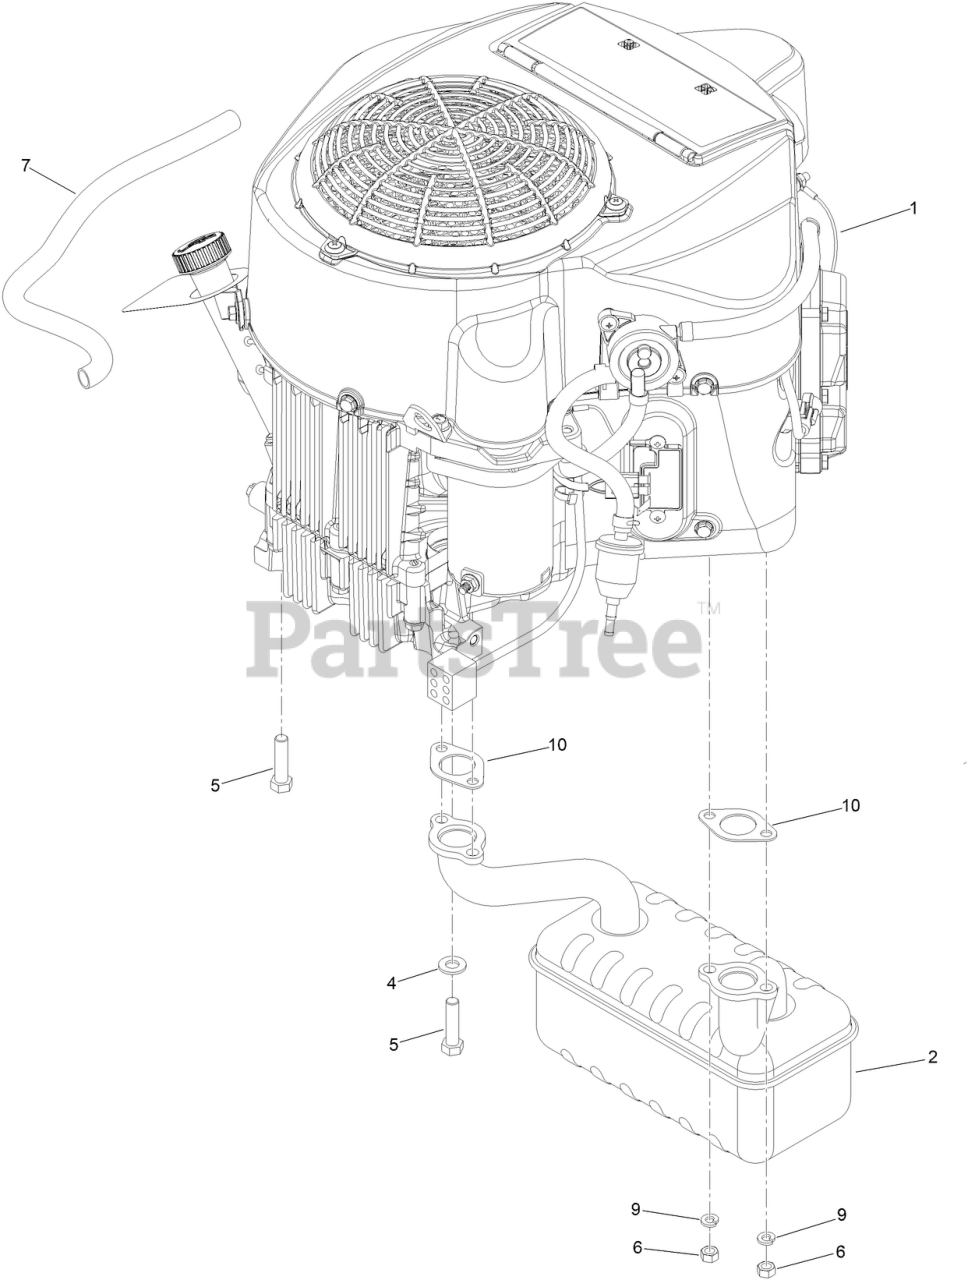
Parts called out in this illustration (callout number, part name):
2	MUFFLER
4	WASHER-FLAT
5	BOLT-HH
7	TUBE-DRAIN, OIL
9	WASHER-LOCK
10	GASKET-EXHAUST
